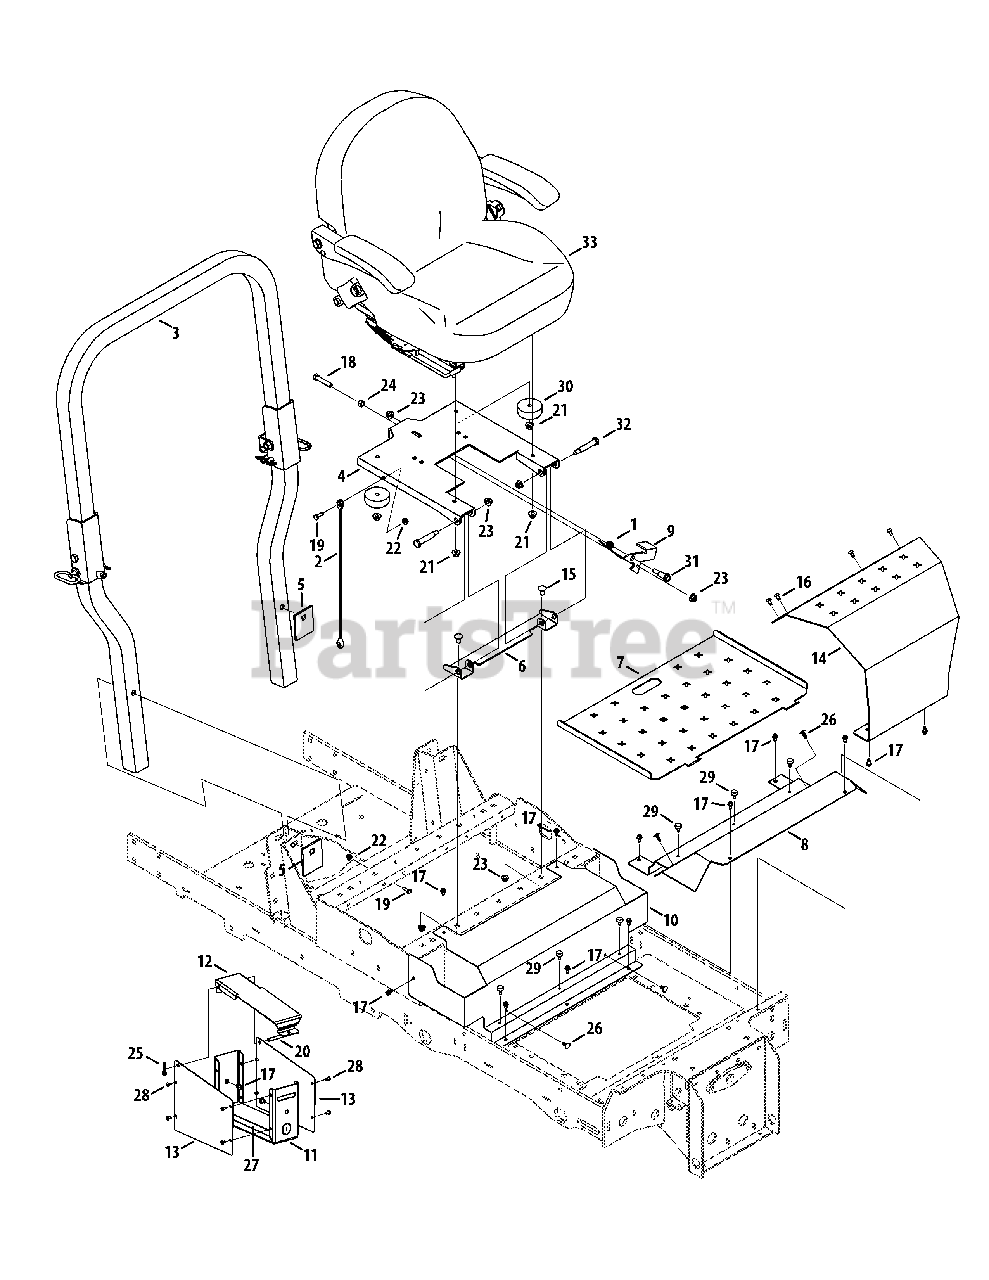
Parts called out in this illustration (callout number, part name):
1	Torsion Spring, .725 x 1.0 x .09
2	Cable Support
3	Folding ROPS Assembly
4	Seat Mounting Bracket
5	Deck Reinforcement Plate
6	Seat Mounting Bracket
7	Floor Panel Tray
8	Floor Panel
9	Seat Lever Latch
10	Control Panel Cover
12	Storage Box Lid
13	Storage Box Side Panel
14	Front Panel Cover
15	Carriage Bolt, 3/8-16 x .75
16	Screw, 1/4-20 x .5
17	Hex Flange Screw, 1/4-20 x .500
18	Hex Cap Screw, 3/8-16 x 2.25
19	Hex Cap Screw, 1/4-20 x .75
20	Clevis Pin, .25 x 3.5
21	Nut, 5/16-18, Flangelock
22	Nut, 1/4-20, Flangelock
23	Nut, 5/16-18, Flangelock
24	Nut, 3/8-16, Hex
25	Cotter Pin, Bow Tie
26	Clip, .250 Dia.
27	Adhesive Pad
28	Rivet, 3/16 x .325
29	Bumper, .62 Dia. x .3
30	Rubber Bumper, 2.5 x 1.0
31	Shoulder Bolt, .50 x .925, 3/8-16
32	Shoulder Bolt, .500 x 2.23, 3/8-16
33	Seat, w/arms
